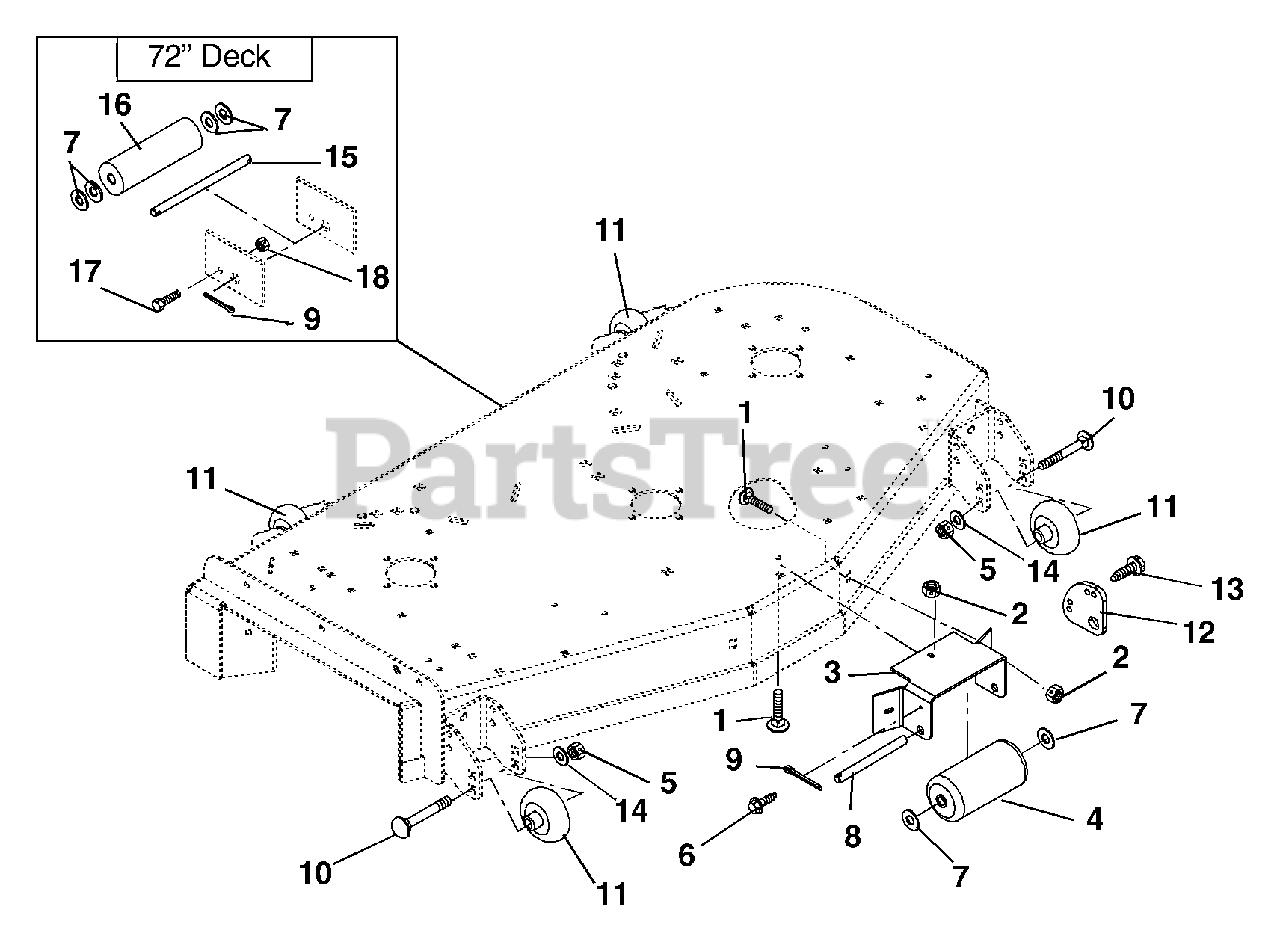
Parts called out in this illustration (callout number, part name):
1	Bolt-Round Head Square Neck .38-16 x 1.00 Grade 5
2	Nut-Locking-Top-Flange .38-16
3	Bracket- Anti-Scalp Roller
5	Nut-Locking-Nylon .50-13
6	Screw-Tapping .25-20 x .75 Hex Washer Head
7	Washer-Flat-Steel .656 x 1.31 x .095 (058, 060, 318, 319)
7	Washer-Flat-Steel .656 x 1.31 x .095 (059, 061)
9	Pin-Cotter .25 x 2.00 (058, 060, 318, 319)
9	Pin-Cotter .25 x 2.00 (059, 061)
10	Bolt-Round Head Square Neck .50-13 x 5.00 Grade 2
11	Wheel, 3 x 5
12	Anti-Scalp Washer
13	Screw-Tapping .25-20 x .62 Hex Washer Head
14	Washer-Flat-Steel .531 x 1.06 x .095
15	Shaft, Center Roller (059, 061)
16	Roller, Gage (059, 061)
17	Bolt-Hex .25-20 x .75 Grade 5 (059, 061)
18	Nut-Locking-Center .25-20 (059, 061)
